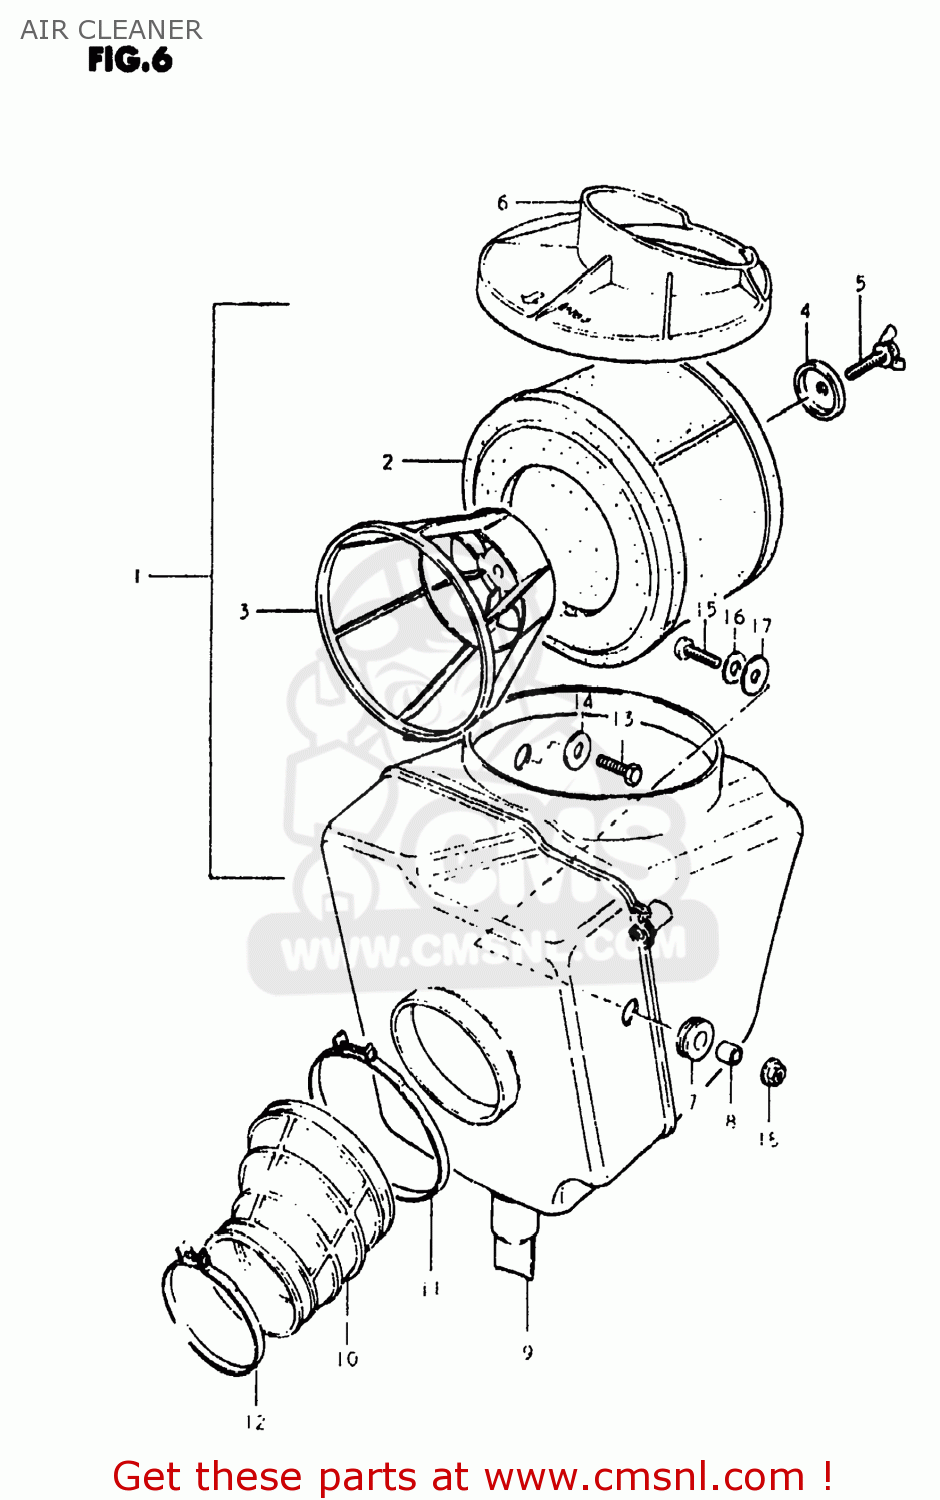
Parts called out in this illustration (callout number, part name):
1	CLEANER ASSEMBLY,AIR
2	FILTER
3	HOLDER
4	HOLDER,FILTER
5	WING BOLT,AIR CLEANER
6	CAP,AIR CLEANER
7	CUSHION
8	SPACER (6.1X9X9)
9	DRAIN TUBE,AIR CLEANER
10	TUBE,AIR CLEANER OUTLET
11	CLAMP
12	CLAMP
13	BOLT
14	WASHER (6.5X20X1.2)
15	SCREW
16	WASHER
17	WASHER
18	NUT
